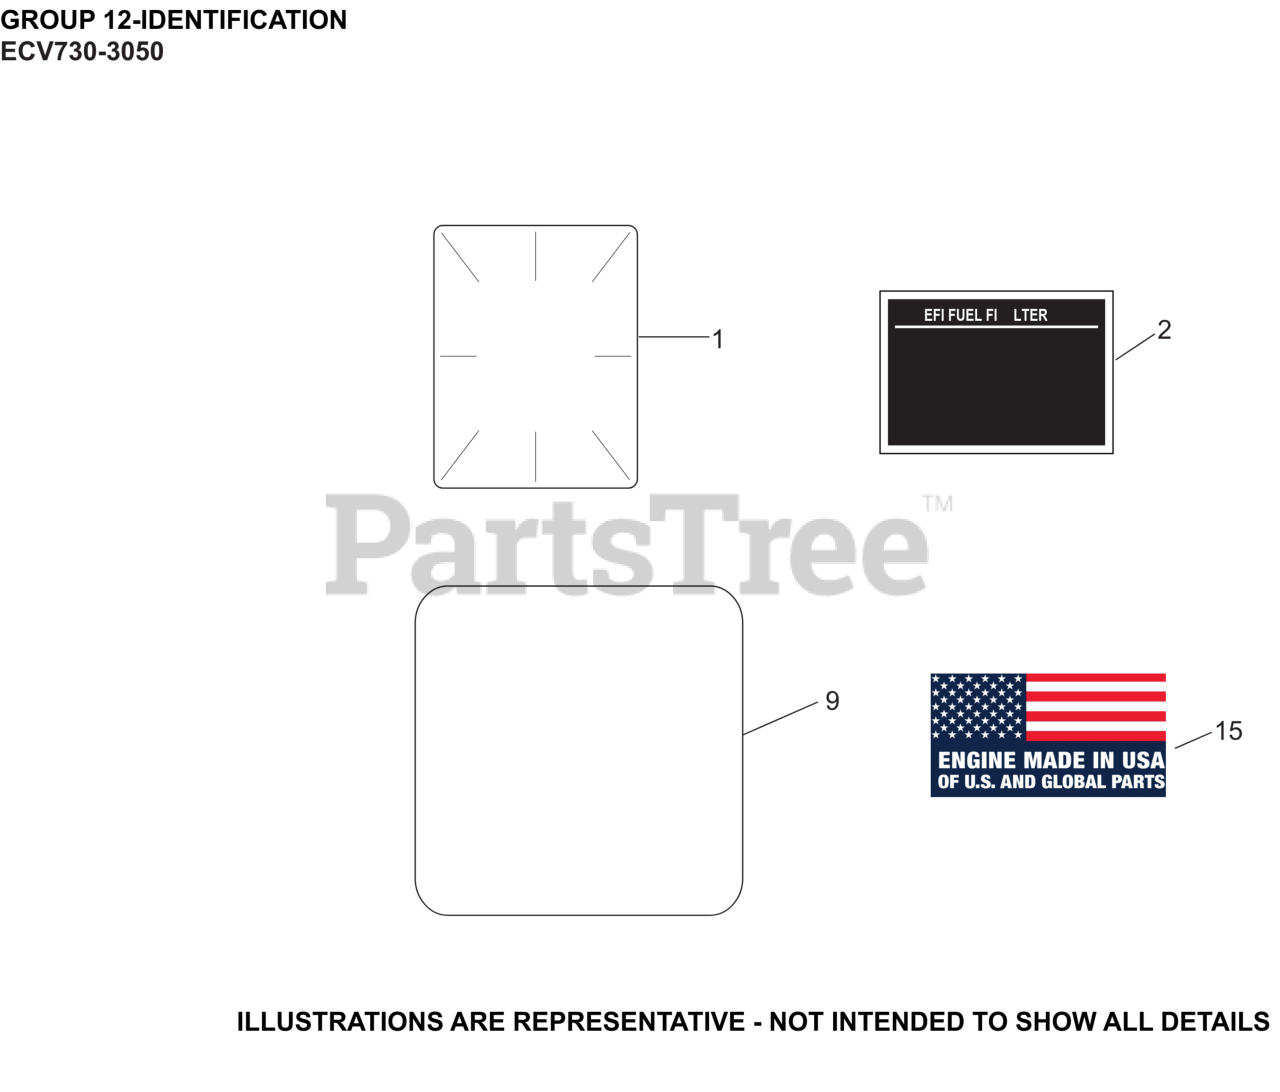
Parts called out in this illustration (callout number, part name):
1	LABEL, CLEAR LAMINATION
2	LABEL, EFI FUEL FILTER
9	DECAL HDAC, 23 HP/747cc/ECV-ECH730
15	DECAL, USA
